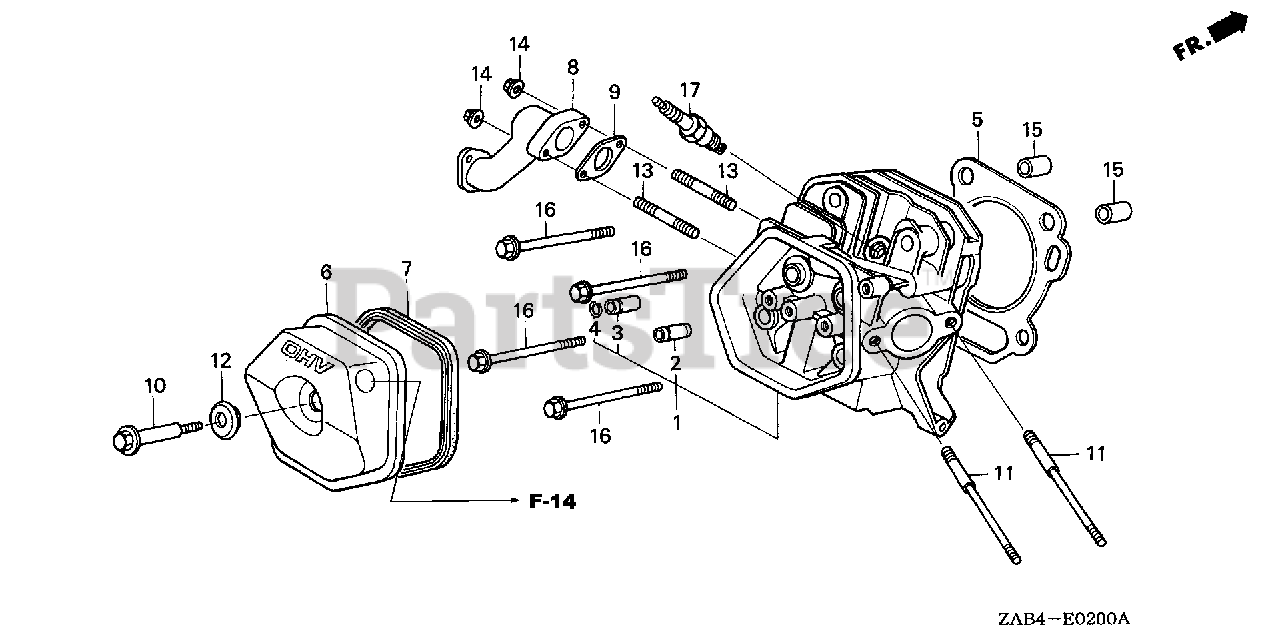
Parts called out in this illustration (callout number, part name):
1	CYLINDER HEAD
2	GUIDE, VALVE (OS)
4	CLIP, VALVE GUIDE
5	GASKET, CYLINDER HEAD
6	COVER, HEAD
7	GASKET, CYLINDER HEAD COVER
9	GASKET, EX. PIPE
9	GASKET, EX. PIPE (WACKER)
10	BOLT, HEAD COVER
11	BOLT, STUD (8X106)
12	WASHER, HEAD COVER
13	BOLT 2, STUD (8X32)
14	NUT, FLANGE (8MM)
15	PIN A, DOWEL (12X20)
16	BOLT, FLANGE (10X80)
17	SPARK PLUG (BPR6ES) (NGK)
